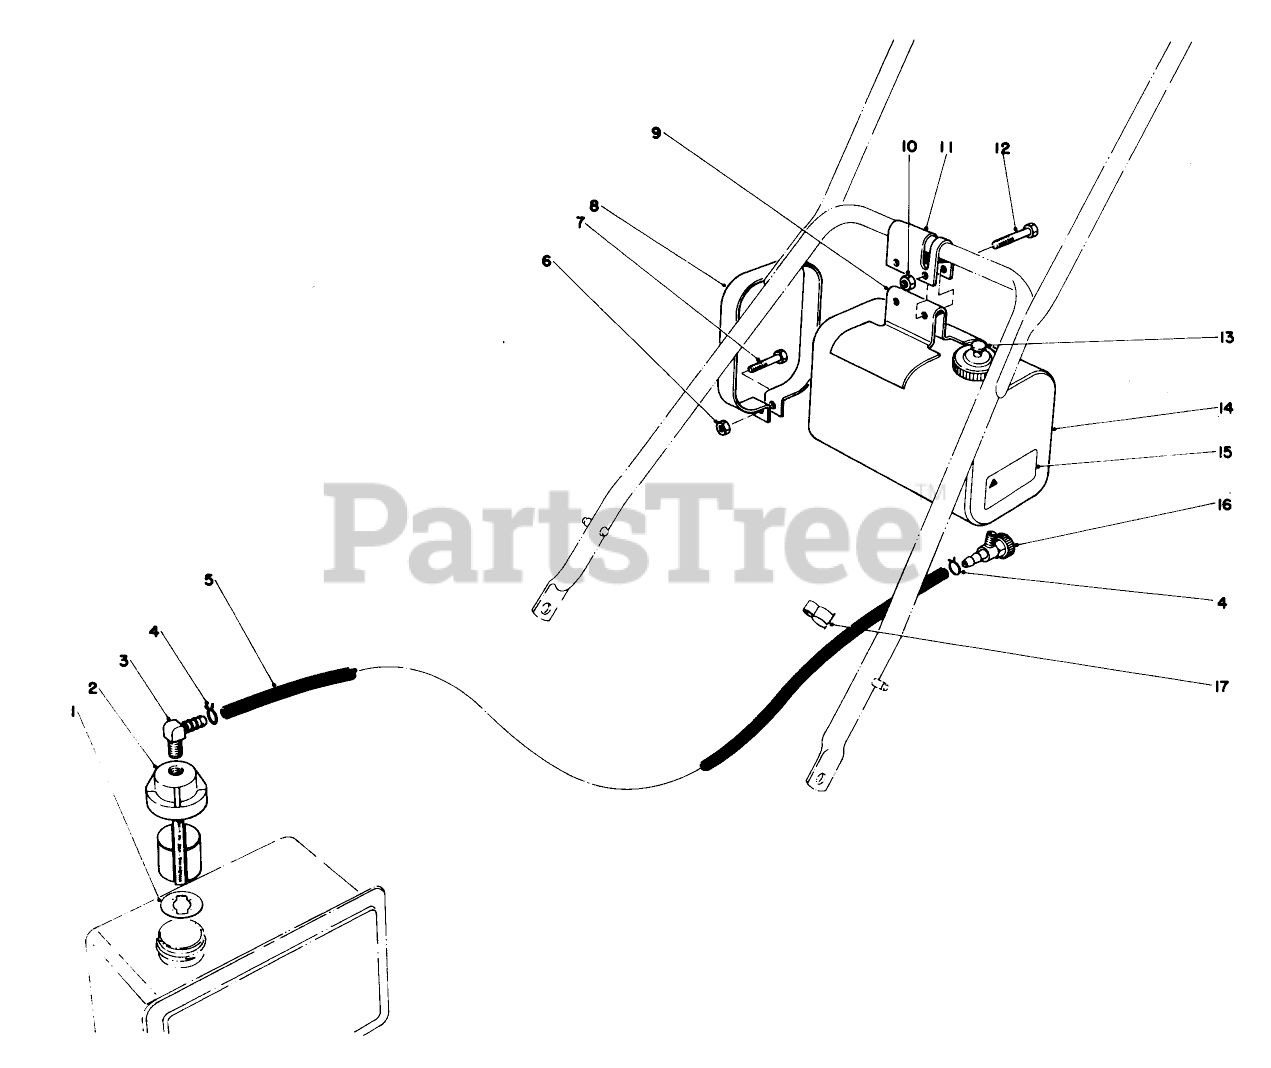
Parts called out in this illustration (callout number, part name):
2	FUEL CONT VALVE ASM
3	CONNECTOR-HOSE
7	SCREW-HH
12	SCREW-HH
